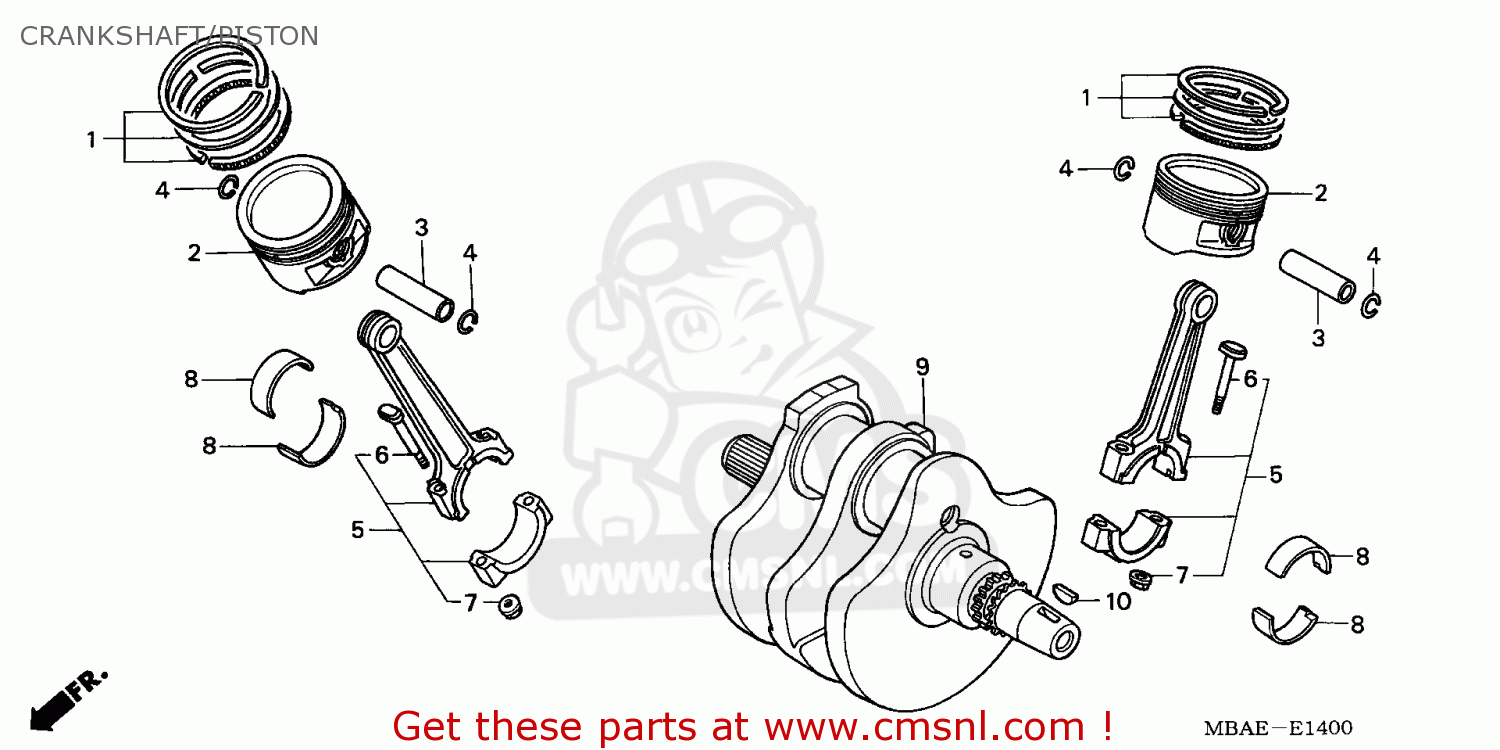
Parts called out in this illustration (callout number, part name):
1	RING SET,PISTON
2	PISTON
3	PIN,PISTON
4	CLIP 18MM,PISTON
5	CONN ROD ASSY
6	BOLT CONN ROD
7	NUT,CONNECTIONG R
8	BRG A CONNROD
9	CRANKSHAFT COMP
10	KEY,SPL.WOODRUFF
